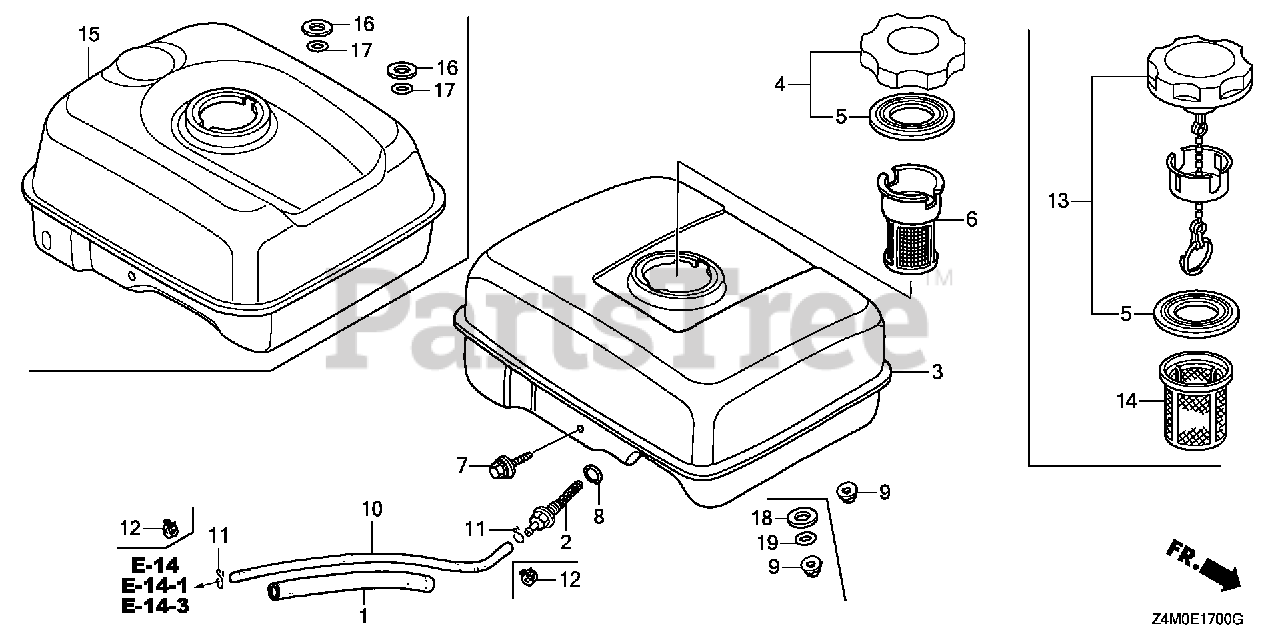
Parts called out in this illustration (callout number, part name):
1	RUBBER, SUPPORTER (107MM)
2	JOINT, FUEL TANK
3	TANK, FUEL *NH31* (MCKINLEY WHITE)
5	GASKET, FUEL FILLER CAP (39X62X3) (RADICON)
7	BOLT, FLANGE (6X29)
8	O-RING (13.5X1.5) (ARAI)
8	O-RING (14MM) (NOK)
9	NUT, FLANGE (6MM)
10	TUBE, FUEL (4.5X145) (FKM)
12	CLAMP, TUBE (D8)
13	CAP, FUEL FILLER
14	FILTER, FUEL
15	TANK, FUEL *NH31* (MCKINLEY WHITE)
